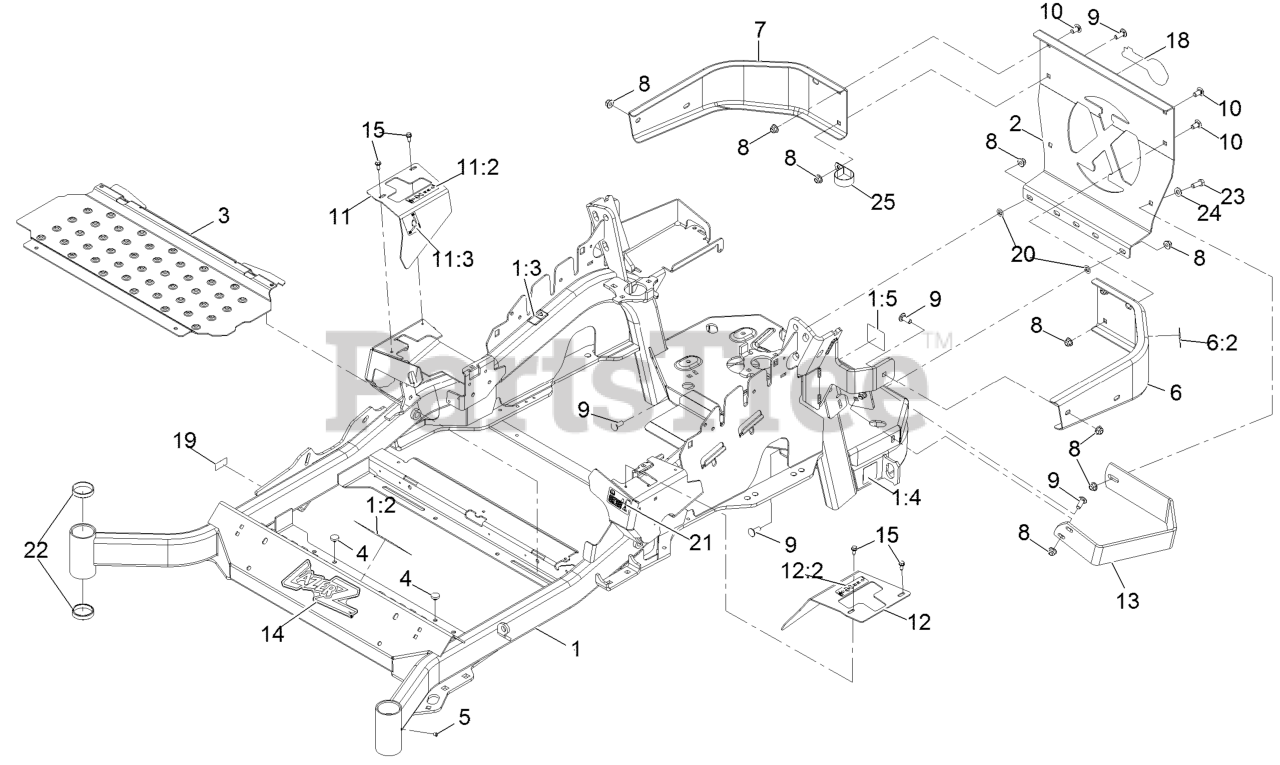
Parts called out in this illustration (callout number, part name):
1	MAINFRAME ASM
1:2	DECAL-DANGER SLOPE W/ROPS
1:3	DECAL-WARNING
1:4	DECAL-HAZARD, PINCHED FINGER
1:5	DECAL-SPARK ARRESTER
2	PLATE,REAR GUARD
6	LH BUMPER ASM
6:2	DECAL-WARNING
7	BUMPER-RH
8	NUT-HF, NI
9	SCREW-CARR
10	SCREW-CARR
11	RH MOTION CONTROL COVER ASM
11:2	DECAL-CONTROL, MOTION
11:3	DECAL-PARK BRAKE, CE
12	LH MOTION CONTROL COVER ASM
12:2	DECAL-CONTROL, MOTION
13	GUARD-MUFFLER
14	DECAL,LAZER MODEL
15	SCREW-HWH
19	Decal-Patent Ttco.Com
20	NUT-PUSH
21	DECAL-FUEL FILL, CE
22	CUP-BEARING
23	SCREW-HH
24	WASHER-FLAT
25	CLAMP-R
